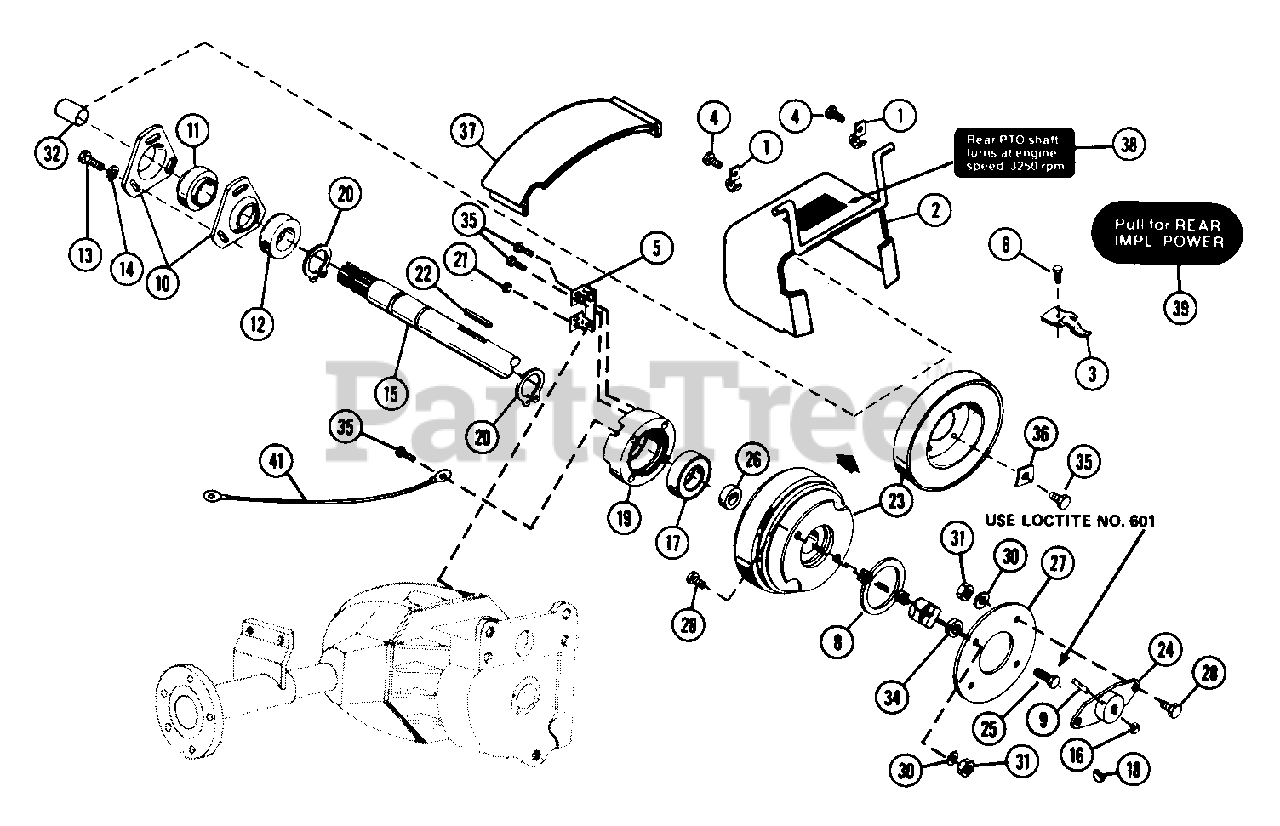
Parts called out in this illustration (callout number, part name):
2	PTO SHIELD
3	SNAP FASTENER
4	SCR-TAP .250-20X.50 HXSLHDPL
5	TORQUE BRACKET ASSEMBLY
6	SCR-TAP 10-24X.375 HWH PL TR
8	PILOT PLATE
9	LOCK STUD
10	BEARING FLANGE
11	BRG/W COLLAR 1.0 X 2.047 X.844
12	BEARING COLLAR
13	BLT-HEX .31-18X.75 PL GR2
14	WSHR-LK .312X.097 PL HVY
16	NUT-LK TOP .375-16 GR C YWZC
17	BRG-BALL 1.0X2.0X.56
18	KEY-WDRF .188X.75X.313 SAE 9
19	BEARING MOUNT
20	RG-RTNG-EXT 1.00X.078
21	NUT-LK-CTR .312-24 PL
22	KEY-SQ .25X1.0X.25 SAE 8630
23	ELECTRIC CLUTCH
24	COUPLING
25	BLT-BTHD .38-16X1.25 GR5
26	SPACER 1.006X1.438X.306
27	SPACER COUPLING
28	BLT-HEX .31-18X.75 PL GR2
30	WSHR-FL-STL.344X.688X.065PL
31	NUT-LK .312-18 GR A PL
32	SHAFT COVER
34	RETAINER
35	SCR-TAP 10-24X.75 T-PH PL TR
36	RETAINER CLIP
38	REAR PTO DECAL - 3200 RPM
39	REAR IMPLEMENT DECAL
41	GROUND WIRE
42	CLUTCH SWITCH
44	CLUTCH HARNESS
